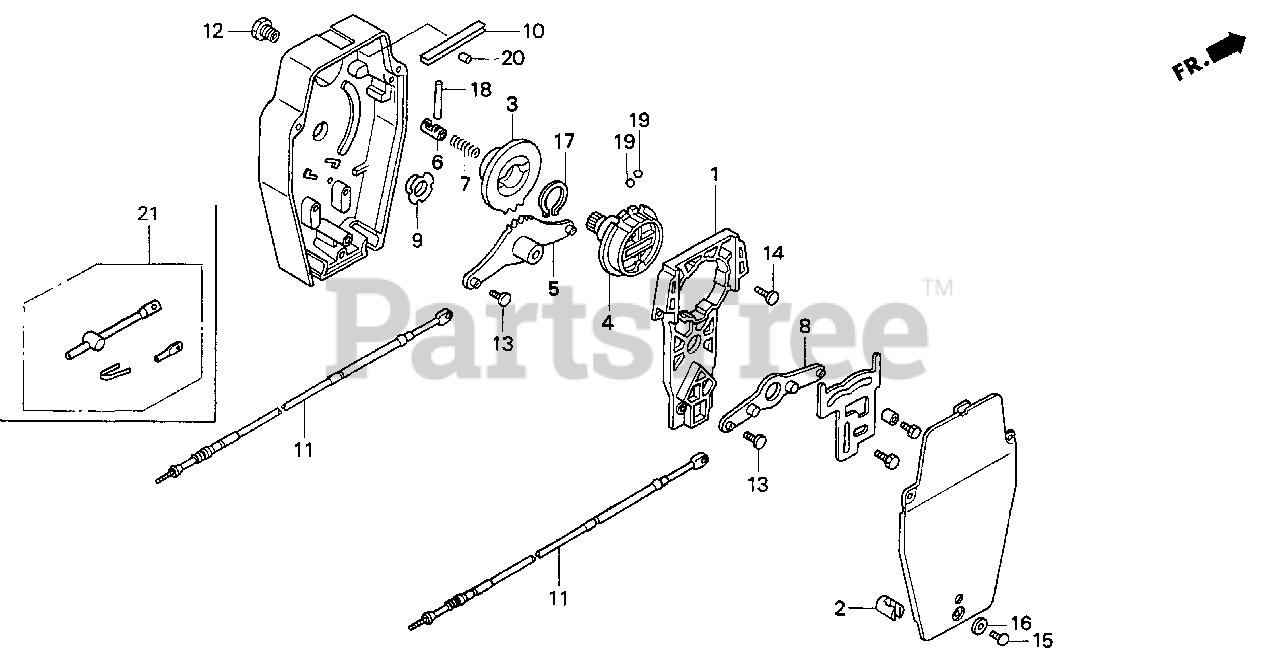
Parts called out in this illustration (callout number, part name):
1	FRAME ASSY., REMOTE CONTROL
3	WHEEL, CONTROL
4	SHAFT, HANDLE
5	ARM ASSY., SHIFT LINK
6	SHAFT, GEARSHIFT
7	SPRING, GEARSHIFT
8	ARM ASSY., THROTTLE LINK
11	CABLE, REMOTE CONTROL (10')
11	CABLE, REMOTE CONTROL (11')
11	CABLE, REMOTE CONTROL (12')
11	CABLE, REMOTE CONTROL (13')
11	CABLE, REMOTE CONTROL (14')
11	CABLE, REMOTE CONTROL (15')
11	CABLE, REMOTE CONTROL (16')
11	CABLE, REMOTE CONTROL (17')
11	CABLE, REMOTE CONTROL (18')
11	CABLE, REMOTE CONTROL (19')
11	CABLE, REMOTE CONTROL (20')
13	SCREW (8-32X3/8)
14	SCREW (10-32X5/8)
15	SCREW (10-32X5/8)
17	CIRCLIP (OUTER)
18	PIN, GEARSHIFT
19	BALL, STEEL
20	ROLLER, SHIFT CLICK
21	ADAPTER, REMOCON CABLE
